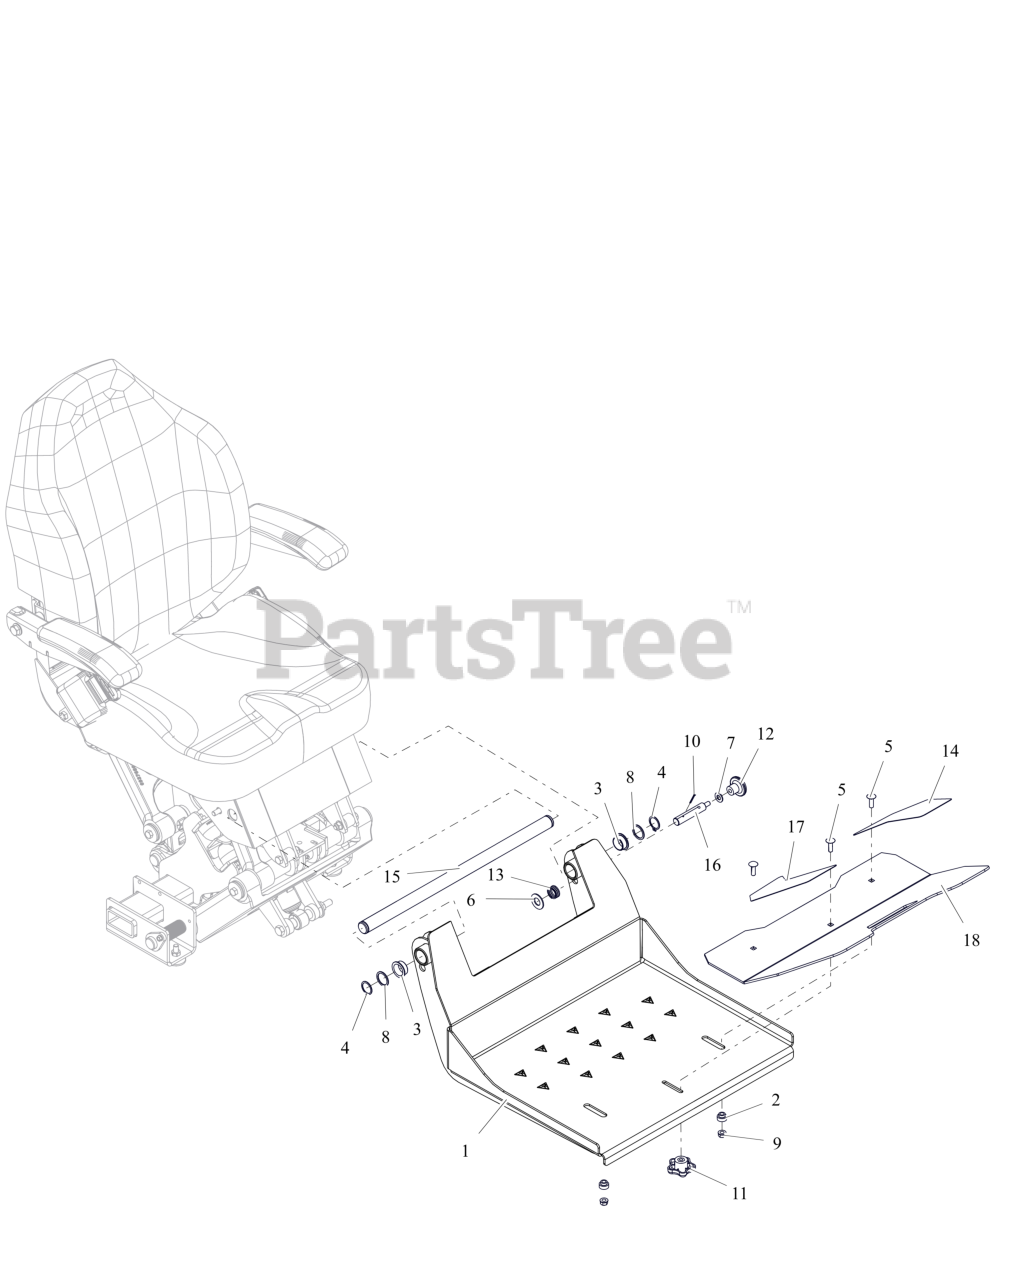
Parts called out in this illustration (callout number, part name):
1	WLDMT, FOOTREST (RED) W/ SAFETY DECAL
2	SPCR, BRG .315X.500X.481X.281
3	BSHG-FLG 1.0X1.125X.50X1.375 R
4	RG-RTNG-EXT 1.00X.042
5	BLT,RHSSN .31-18X1.00 G5 ZCC
6	WSHR-FL-STL 0.649X1.305X0.074 Raw
7	WSHR,FLT .406X.812X.065 ZCC
8	WSHR-FL-STL 1.01X1.25X0.068 ZCC
9	NUT,LK-CTR-FLG .31-18 GF ZCC
10	PIN-COTR .09X1.0 PL
11	KNOB, LOCKING 5/16-18 UNC
12	KNOB, PUSH-PULL .312-18
13	SG-COMP .085X.80X1.00 WLD36
14	ANTI-SKID, LH FOOTREST
15	SHAFT, PIVOT
16	PIN, FOOTREST LOCK-UP
17	ANTI-SKID, FRAME STEP
18	FOOTREST, ADJUSTABLE (RED) W/ SAFETY DECAL
